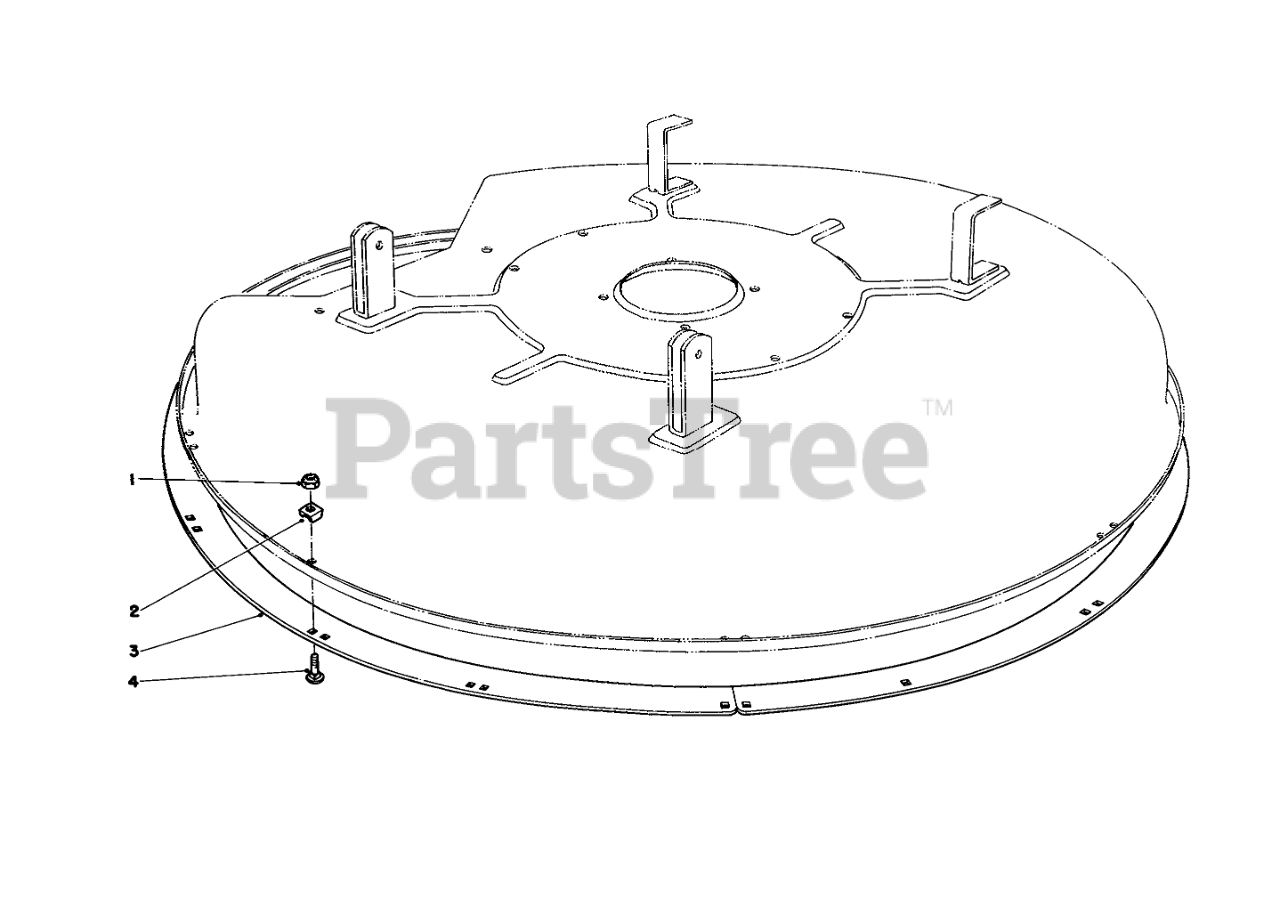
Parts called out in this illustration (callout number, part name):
1	NUT-LOCK, NI
2	DECK RING SPACER
3	DECK RING B
4	BOLT-CARR
